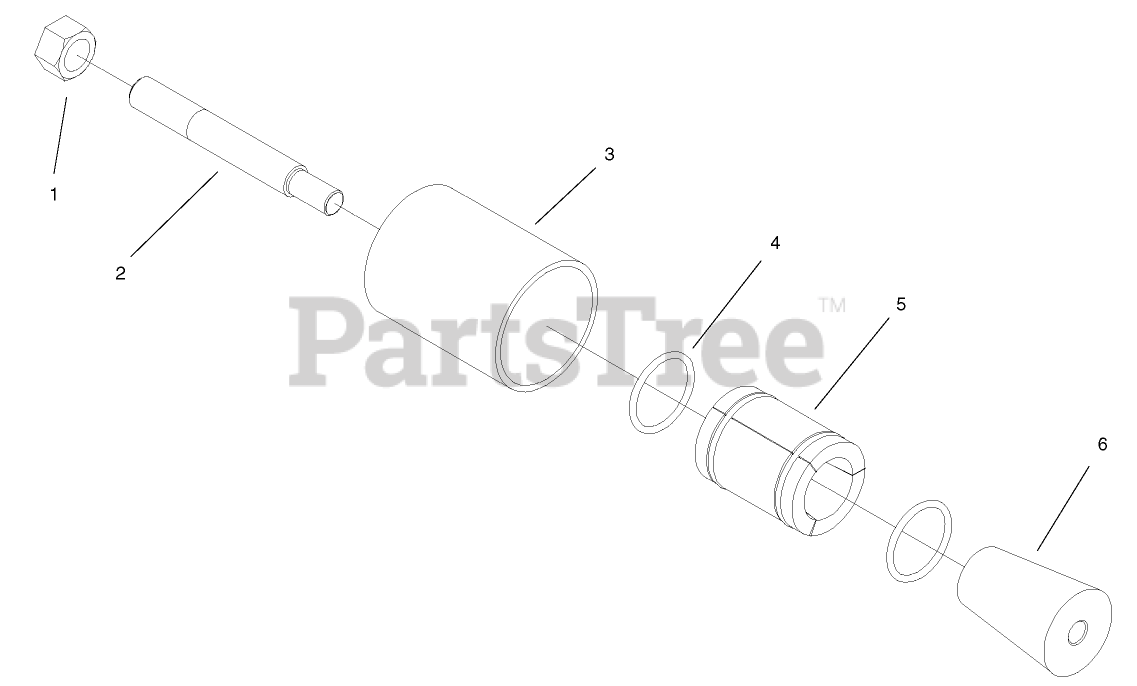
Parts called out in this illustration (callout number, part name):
1	NUT-HEX
2	ROD-PULLER
3	GRIP-OUTER
4	O-RING
5	GRIP-INNER
6	CONE-PULLER
